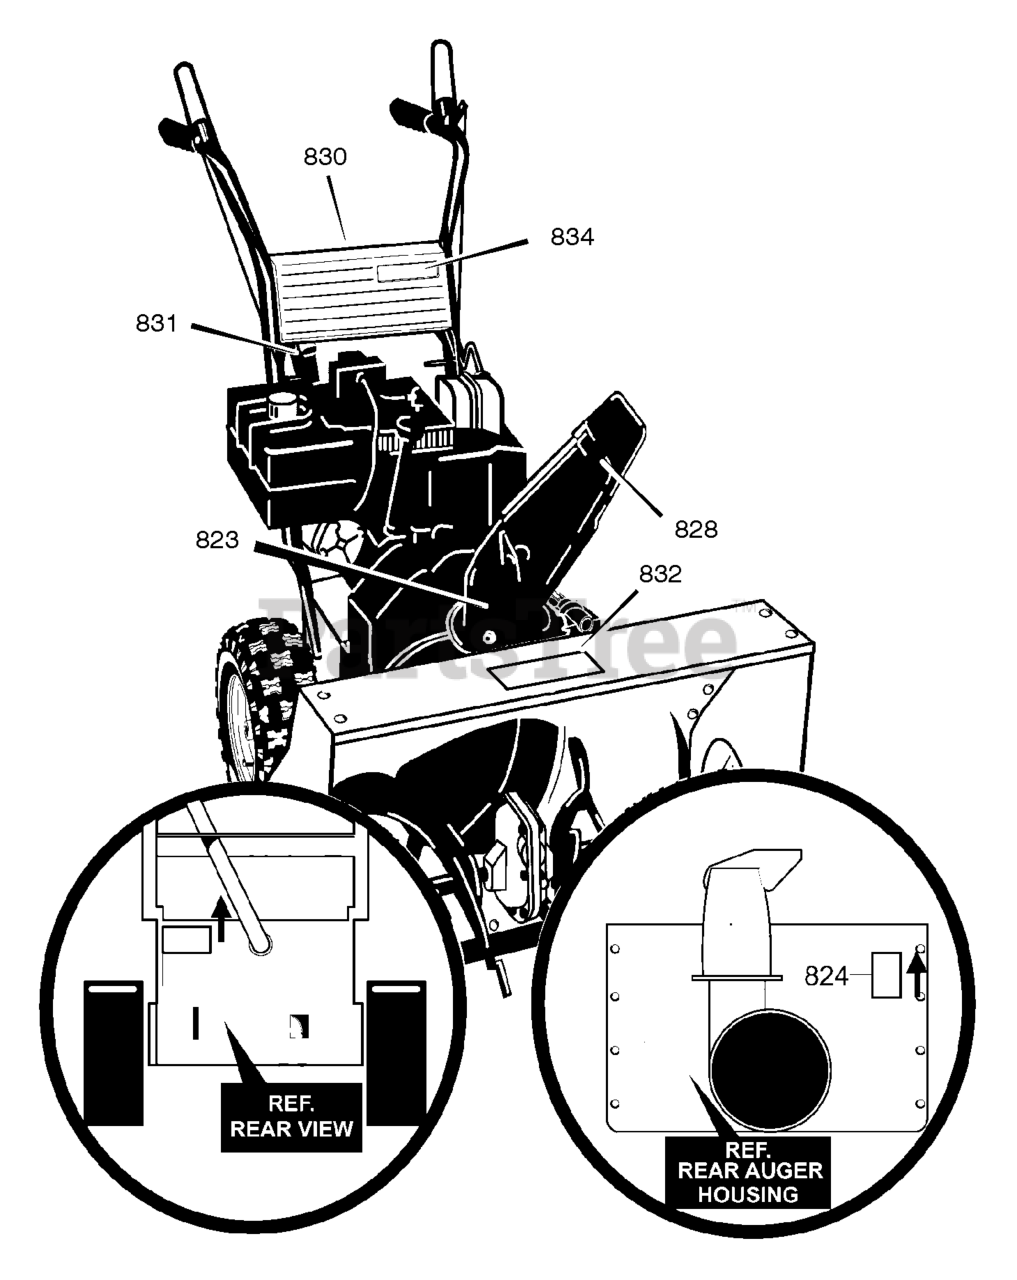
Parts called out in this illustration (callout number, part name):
823	DECAL, DANGER CHUTE HAND
824	DECAL, DANGER FOOT
828	DECAL, THROWN OBJECTS
830	DECAL, TRACTION DRIVE
831	DECAL, GEAR SELECTOR
832	DECAL, MURRAY 5/24
834	DECAL, HANDLE PANEL
